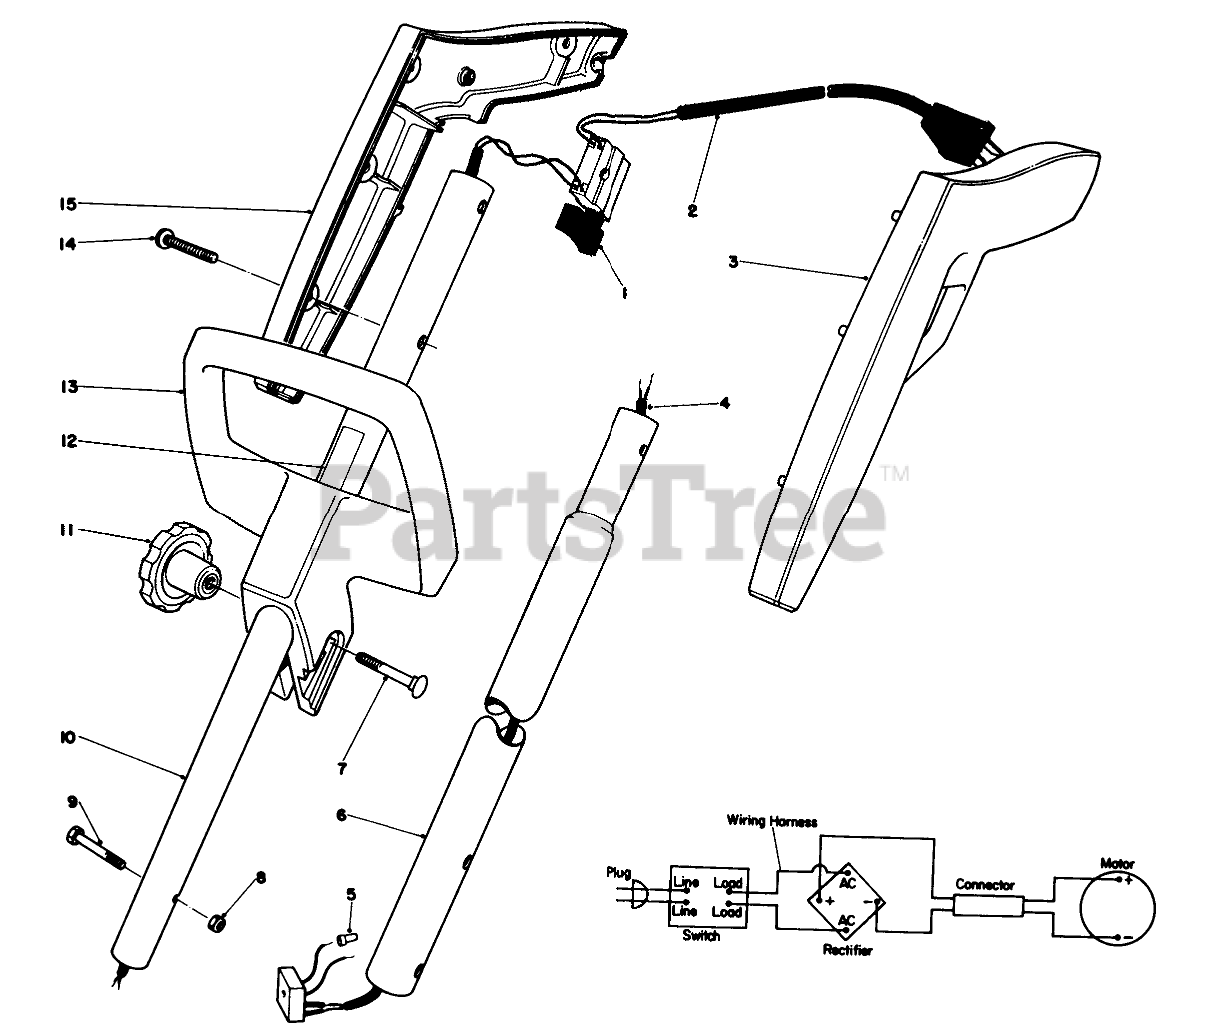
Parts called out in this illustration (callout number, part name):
1	SWITCH SINGLE SPEED
2	Power Cord
3	Grip L.H.
4	Wiring Harness w/Rectifier
5	Wire Connector
6	Tube-Lower
7	BOLT-CARR
8	NUT-LOCK, NI
9	HEX HD MACHINE SCREW
10	Tube-Upper
12	Decal-Caution
13	ADJUSTABLE HANDLE
14	Screw
15	R.H. GRIP
